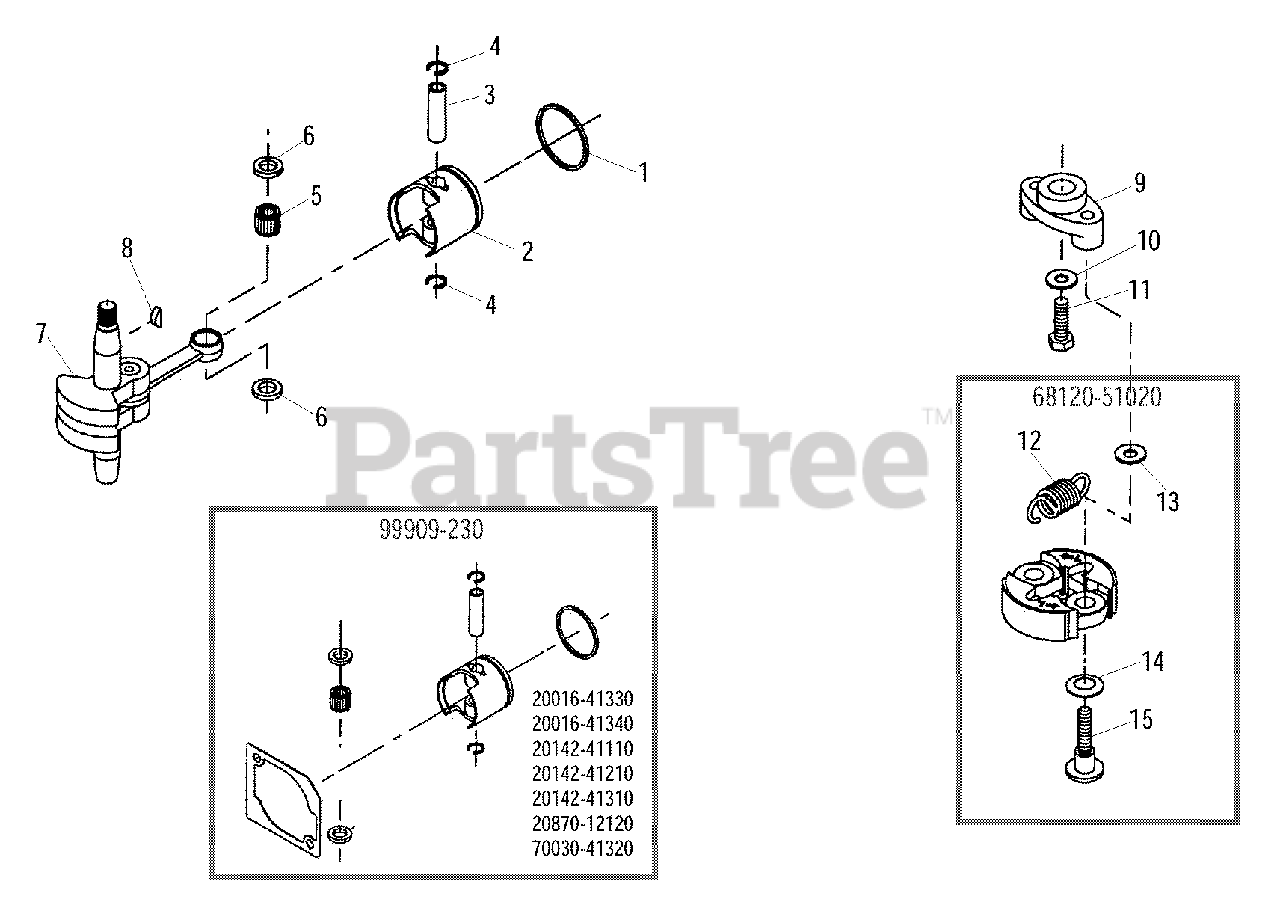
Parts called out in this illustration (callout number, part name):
1	RING, PISTON
2	PISTON
3	PIN, PISTON
4	RING, RETAINING
5	BEARING, NEEDLE
6	WASHER, THRUST
7	CRANKSHAFT ASSY
8	KEY - 3X10
9	HUB, CLUTCH
10	WASHER - 6
11	SCREW - 6X18
12	SPRING, CLUTCH
13	WASHER - 6
14	WASHER - SPRING
15	BOLT, CLUTCH
20870-12120	GASKET, CYLINDER
68120-51020	CLUTCH SHOE ASSY
99909-230	PISTON ASSY
